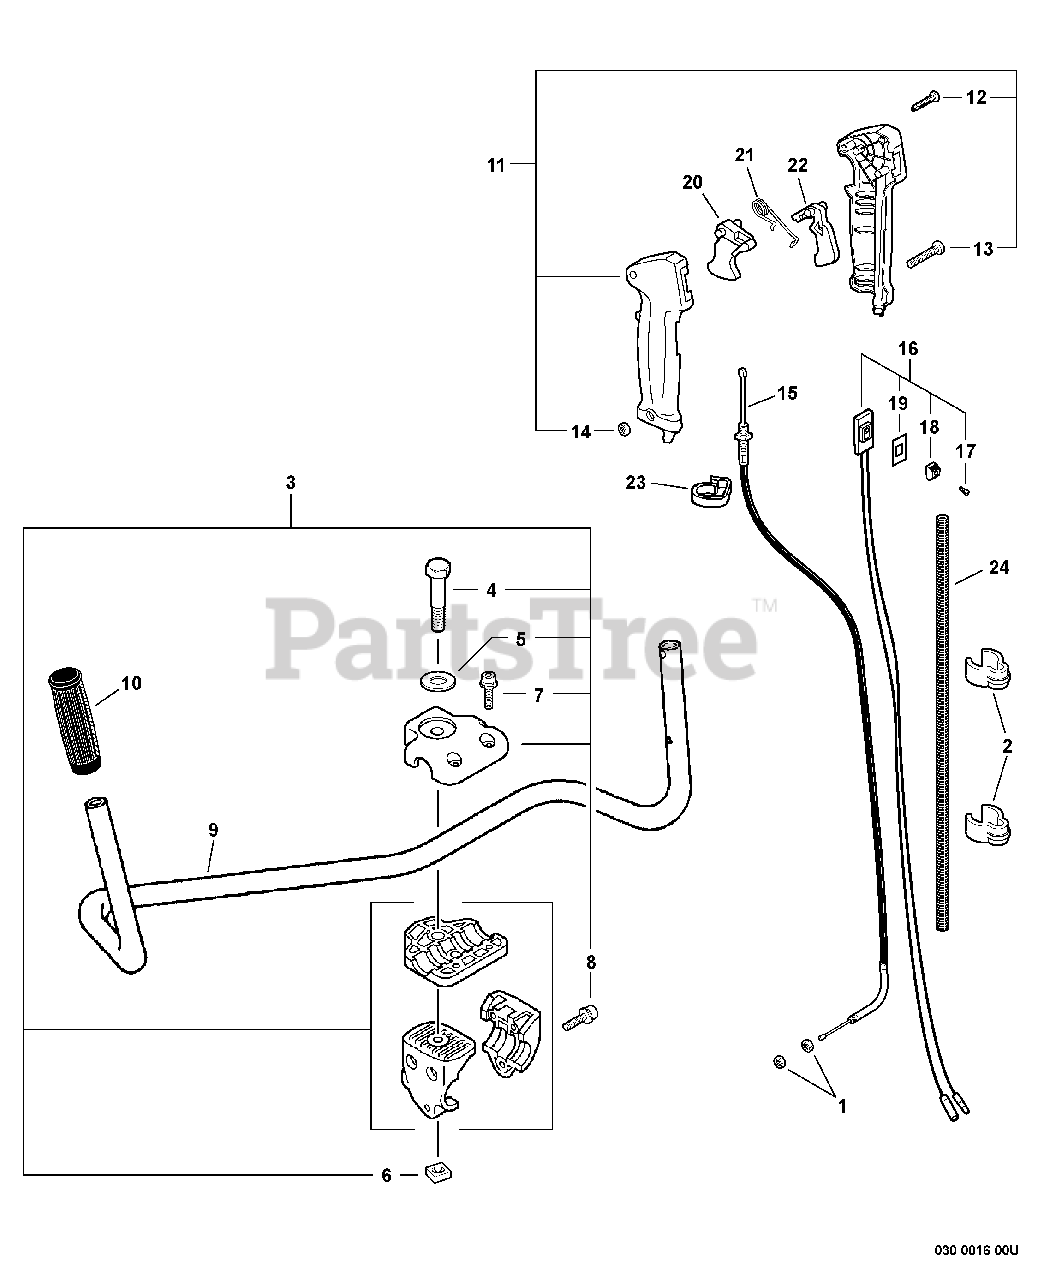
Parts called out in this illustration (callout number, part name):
3	BRACKET KIT, HANDLEBAR
4	BOLT 8×55
5	WASHER 8
6	NUT 8×1.25
7	BOLT 5×20
8	BOLT 5×30
9	HANDLEBAR
10	GRIP, HANDLE
11	CONTROL HANDLE KIT
12	SCREW 3×25
13	SCREW 5×30
14	NUT M5
15	CABLE, THROTTLE
16	SWITCH, ON-OFF
17	SCREW 3×10
18	KNOB, SWITCH - ORANGE
19	LABEL, SWITCH
20	TRIGGER, THROTTLE
21	SPRING, TORSION
22	LOCKOUT, THROTTLE
24	TUBE, FLEXIBLE 7×790
